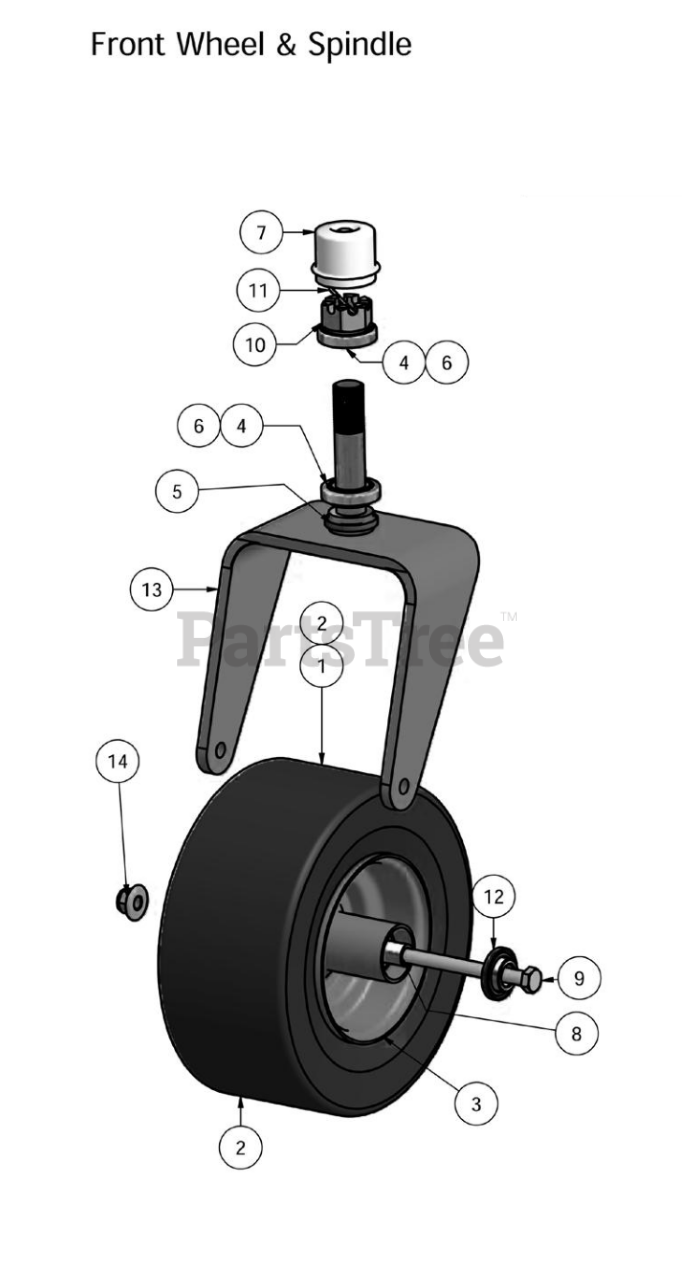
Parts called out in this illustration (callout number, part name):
1	13 x 6.5-6" Tire and Wheel Assembly
2	13 x 6.5-6" Tire ONLY
3	6" Wheel ONLY
7	Dust Cover
8	Wheel Spacer
9	1/2" x 9" Bolt
10	1" Fine Threaded
11	Cotter Pin
12	Wheel Bearing
13	Front Fork with Spindle
14	1/2-13 Nylon Flange Nut
